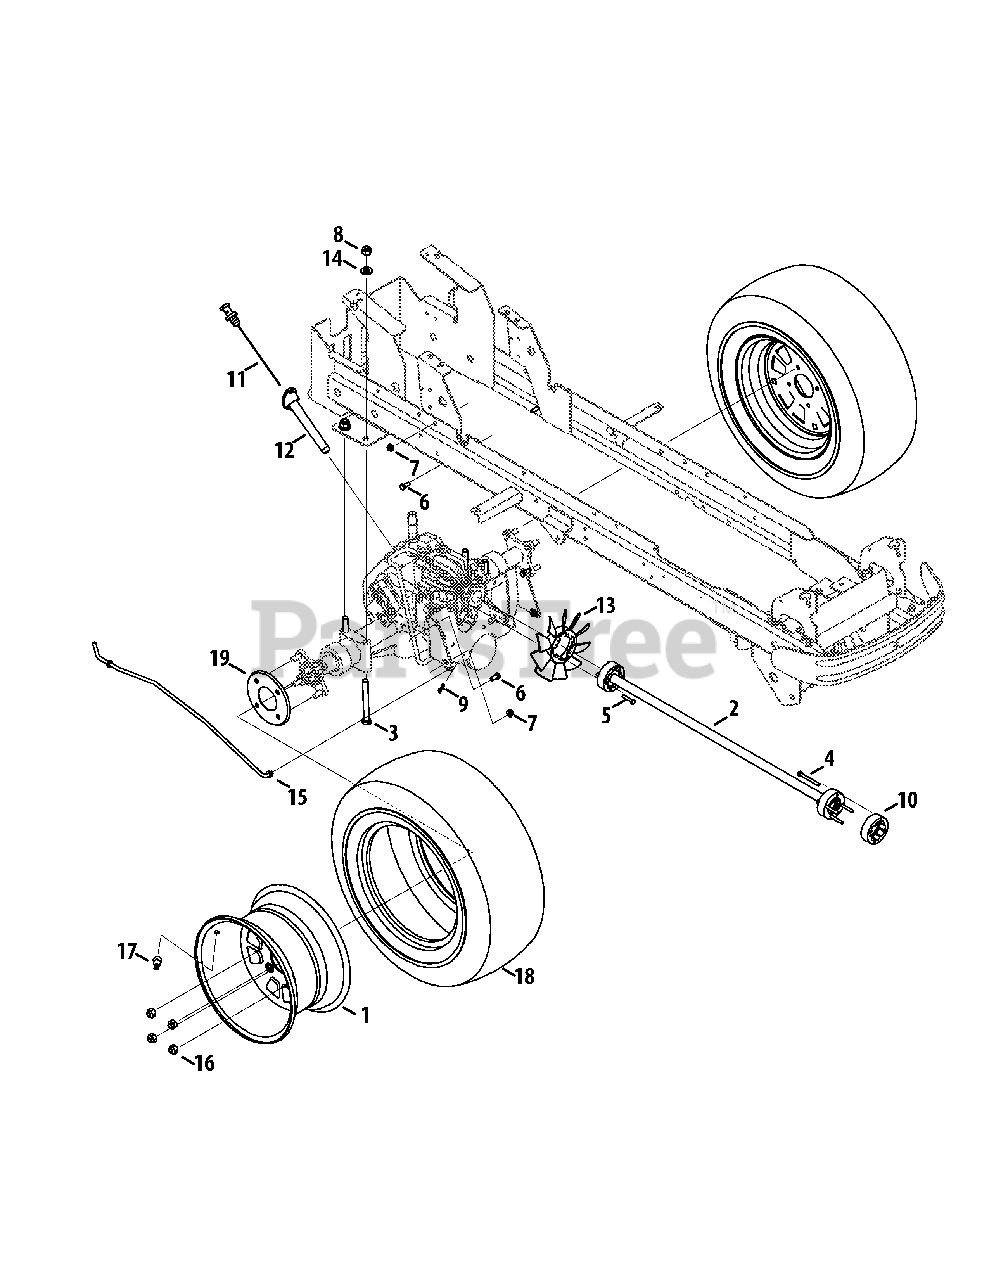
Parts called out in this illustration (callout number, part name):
1	Rim Assembly, 12.0 x 7.0
2	Shaft Assembly, 30.55
3	Hex Screw, 1/2-20 x 4.50
4	Hex Screw, 1/4-20 x 2.50
5	Hex Screw, 1/4-20 x 1.25
6	Hex Screw, 5/16-18 x .75
7	Flange Lock Nut, 5/16-18
8	Hex Lock Nut, 1/2-20
9	Bow-Tie Cotter Pin, 72
10	Drive Shaft Adapter
11	Transaxle Dipstick
12	Dipstick Holder
13	Pump Fan, 7.0
14	Flat Washer, .531 x 1.062 x .134
15	Hydro Relief Lever
16	Lug Nut, 7/16-14
17	Tubeless Air Valve
18	Tire, 23.0 x 10.5 x 12
